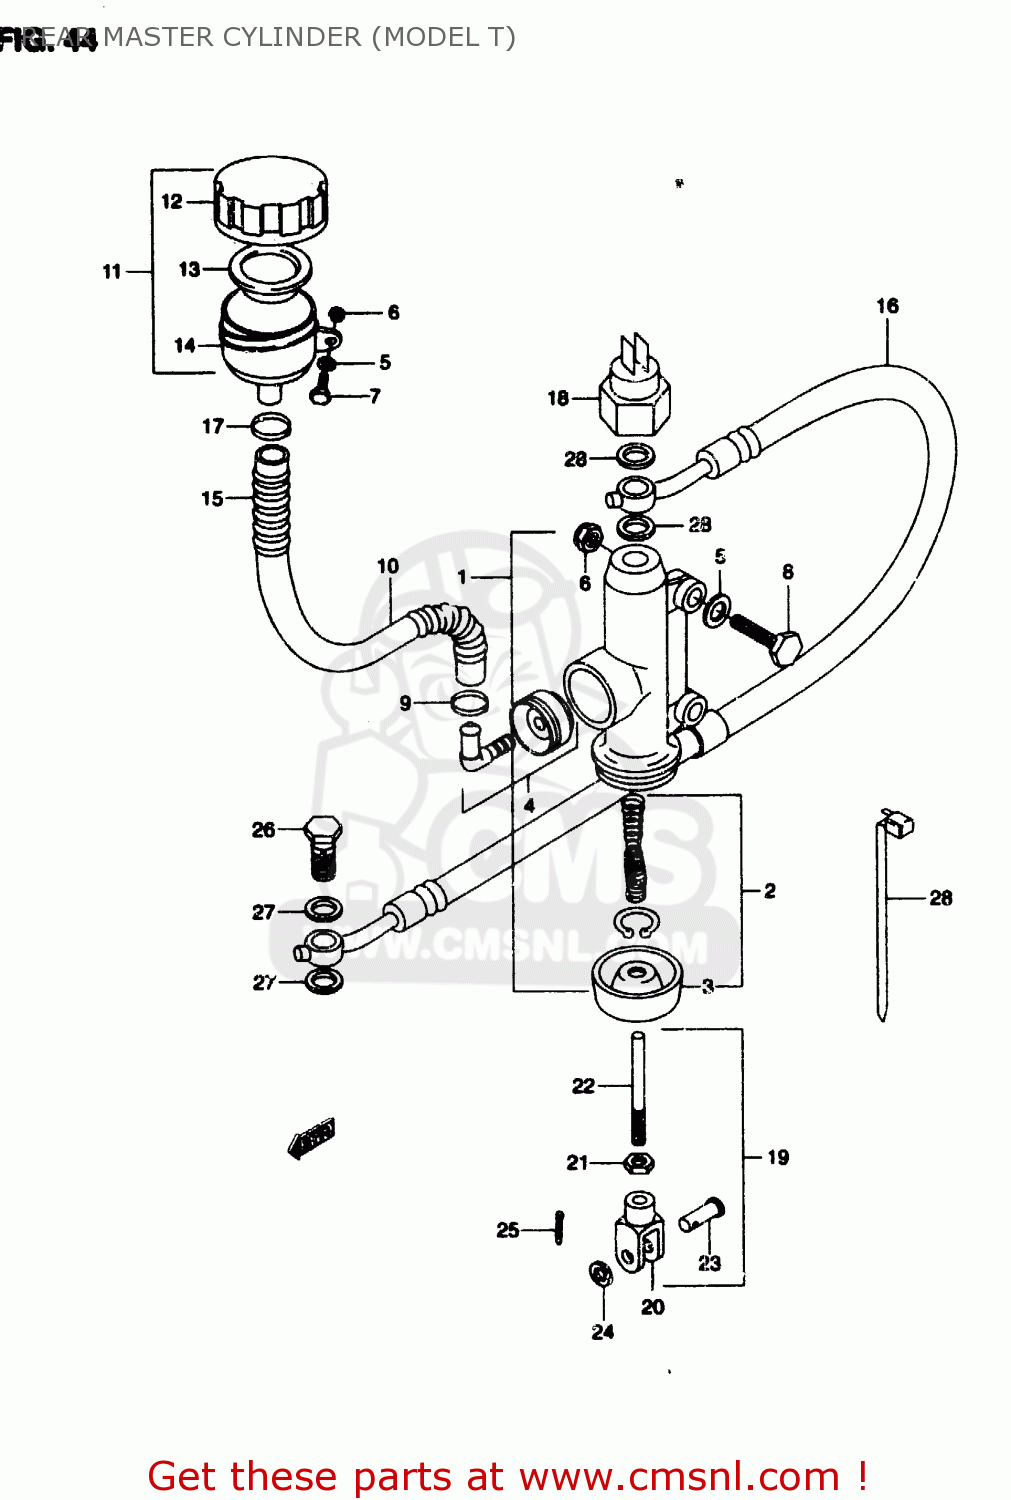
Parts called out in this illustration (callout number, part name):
1	CYLINDER ASSY, REAR
2	PISTON CUP SET
3	YOKE
4	CONNECTOR
5	WASHER
6	NUT
7	BOLT
8	BOLT
9	CLIP
10	HOSE (L:205)
11	TANK ASSY, REAR RESERVOIR
12	CAP
13	DIAPHRAGM
14	TANK
15	SPRING
16	HOSE, REAR BRAKE
17	CLAMP
18	CONTACT
19	PLATE ASSY
20	YOKE
21	NUT 6MM
22	ROD, PUSH
23	PIN
24	WASHER
25	PIN
26	BOLT
27	WASHER
28	CLAMP(L:95)
